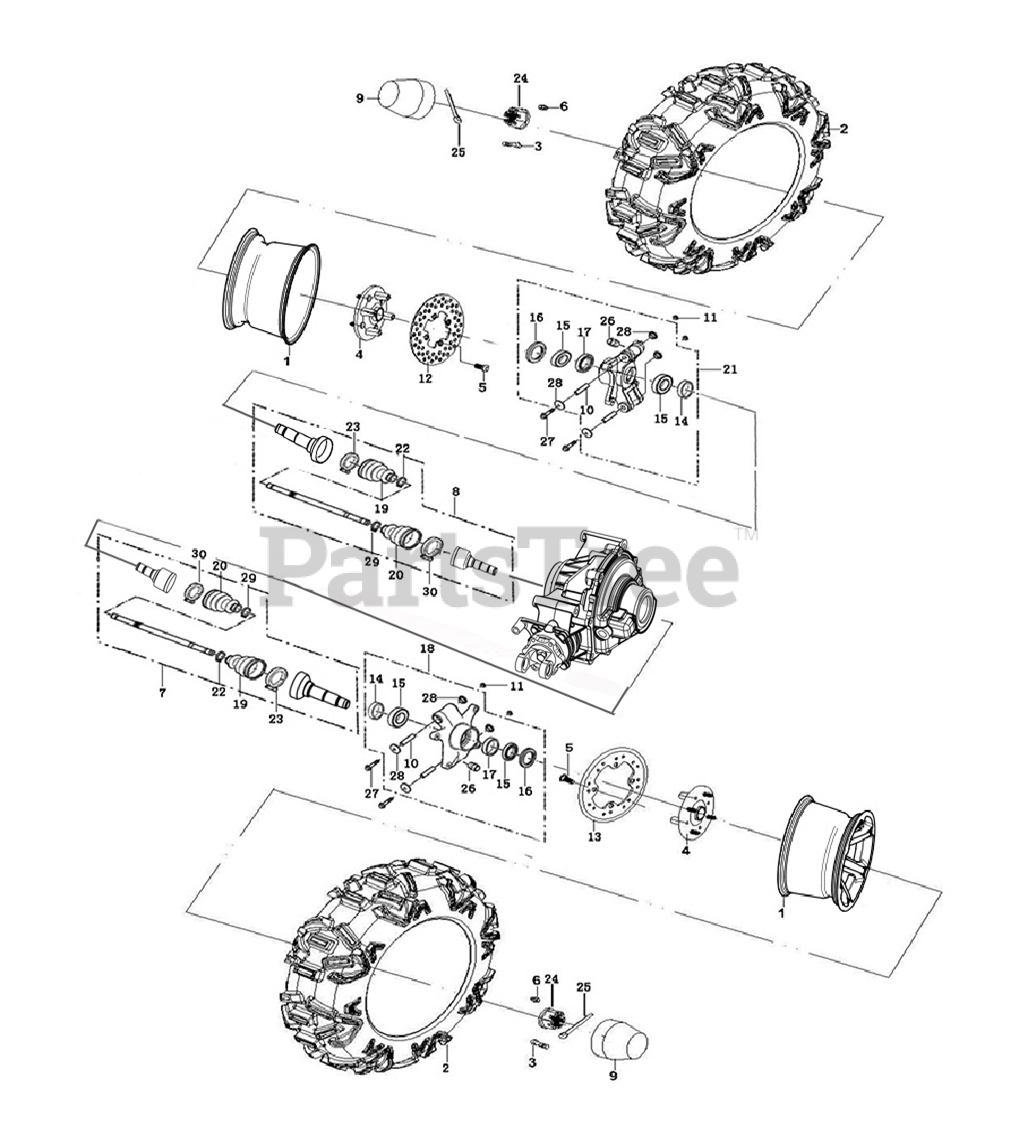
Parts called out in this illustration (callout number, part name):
1	RIM-REAR (14x)8
2	TIRE (REAR CARLISLE)
3	VALVE-CYCLE
5	BOLT M8X15-15X5
6	TAPER NUT M10X1.25
7	REAR LEFT CONSTANT VELOCITY JOINT
8	REAR RIGHT CONSTANT VELOCITY JOINT
9	HUB DUST COVER
10	STEERING KNUCKLE TUBE (REAR)
11	LOCK NUT M10X1.25
12	DISC BRAKE - REAR RIGHT
13	DISC BRAKE - REAR LEFT
14	REAR KNUCKLE INSIDE OIL SEAL
15	BEARING 6206RS
16	REAR KNUCKLE OUTSIDE OIL SEAL
17	REAR STEERING KNUCKLE TUBE
18	STEERING KNUCKLE (REAR LH)
19	RUBBER BOOT
20	AXLE RUBBER BOOT
21	STEERING KNUCKLE (REAR RH)
22	CLAMP - LARGE
23	CLAMP - LARGE
24	SLOTTED NUT M24X1.5
25	COTTER PIN 3.2X50
26	KNUCKLE OIL FITTING
27	HEX HEAD FLANGE BOLT M12X1.25-110
29	CLAMP - LARGE
30	CLAMP - LARGE
